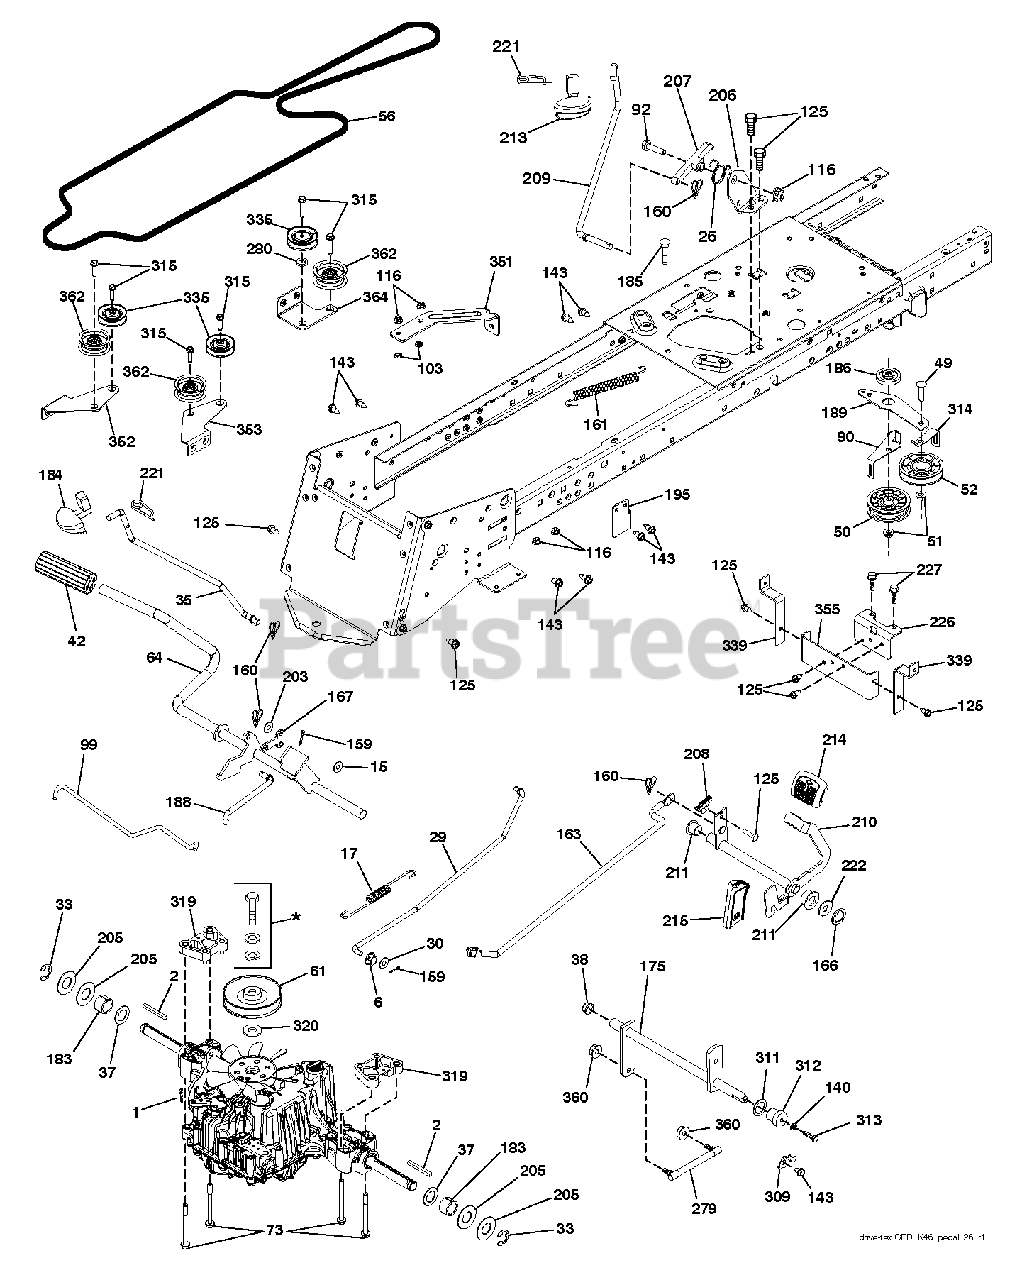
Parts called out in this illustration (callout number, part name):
2	SQUARE KEY
6	GROMMET T
26	SPRING.RETURN.CRUISE
33	E-RING LT
35	ROD.BRAKE.PARTK.HUSQ.TEX
37	WASHER.HARDENED
38	NYLINER SNAP 5/8" ID
42	PEDAL COVER T
49	BOLT
50	IDLER.FLAT.910.OFFSET
51	NUT LOCK FLG 3/8-16 UNC
52	IDLER.V-GROOVE.910.OFFSET
64	SHAFT.ASM.PEDAL.BRK.CNTR
73	BOLT.HEX.FLNG.5/16-18X3.75
92	BOLT
103	JAM NUT TI
116	NUT LOCK HEX FLANGE 5/16-18
125	SCREW
140	LOCKWASHER
159	COTTER PIN
160	RETAINER CLIP
161	SPRING, RETURN LT
166	NUT.PUSH.625
167	LATCH.BRAKE.SPRING
183	SPACER AXLE
184	HANDLE.PARKG.BRK.HUSQ/PRED.667
186	SPACER.RETAINER
188	LINK.CLUTCH.GROUND.DRIVE
203	WASHER
206	BRKT.MOUNT.LATCH.CRUIS
207	LATCH.CONTROL.CRUISE
208	GEAR.SECTOR.CONTROL.CR
209	ROD.CONTROL.CRUISE.GT.
210	ROCKER.ASM.PEDAL.CONTR
211	BEARING.NYLON
213	KNOB.CONTROL.CRUSIE.HU
214	PAD PEDAL FORWARD
221	RETAINER.SPRING.CLIP.H
222	WASHER 21/32 X 1-1/4 X 10 GA.
226	BRACKET.MOUNT.TORQUE.K46.TLT
227	SCREW
309	PLATE FASTENING LT
311	WASHER NYL
314	RETAIN BELT
315	BOLT.5/16-18X1.25
320	WASHER.SPACER.MANDREL
335	PULLEY.V-IDLER.
